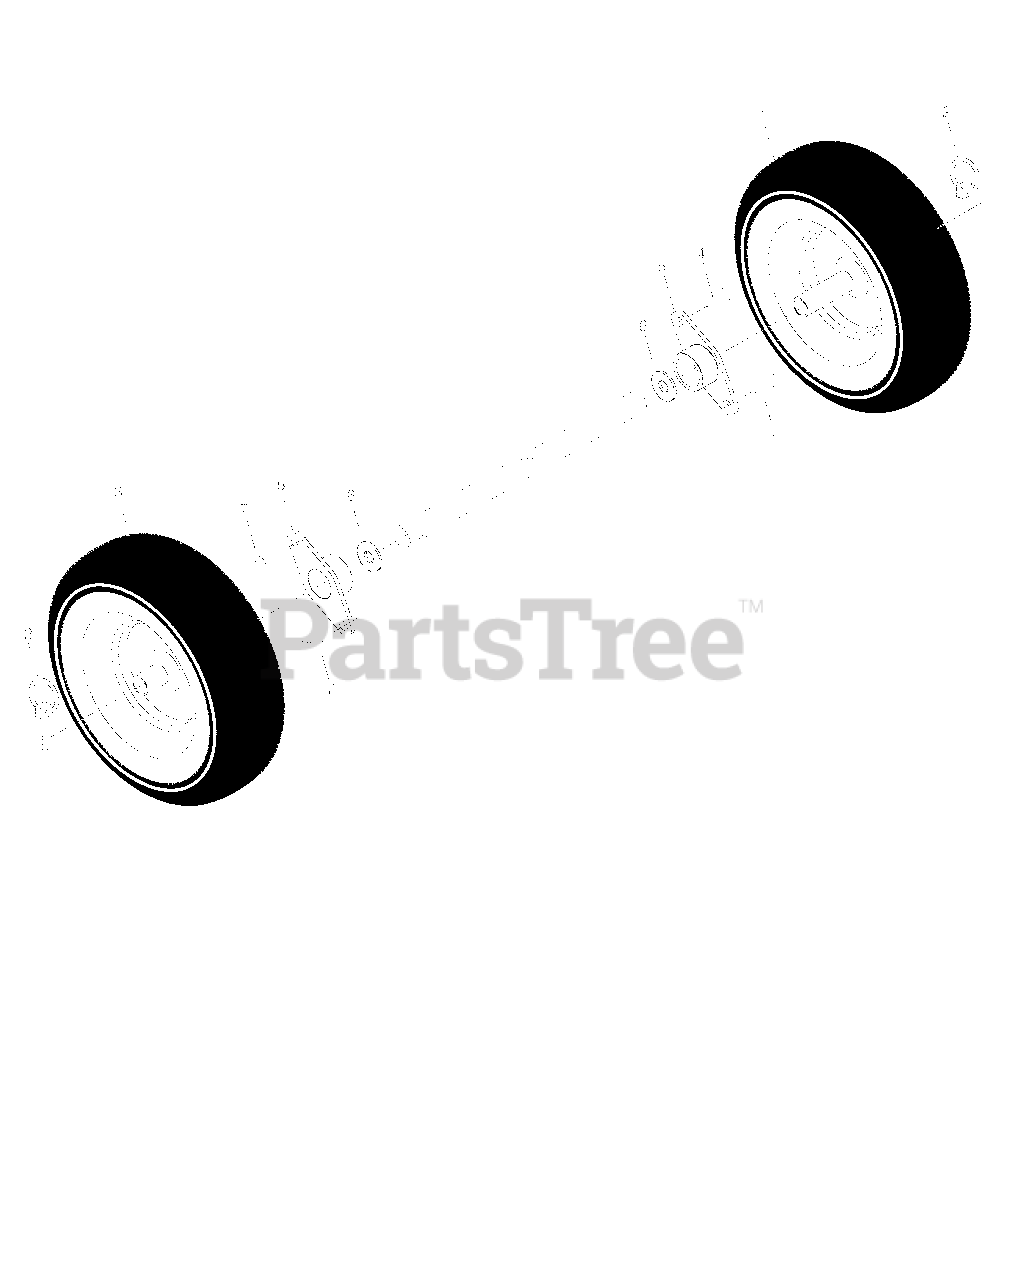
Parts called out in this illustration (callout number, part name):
1	Decal, Danger
2	Decal, Husqvarna
3	Decal, Danger, Deflector
4	Decal, Danger
5	Decal, Husqvarna, 924SBE
6	Decal, Instruction
7	Decal, Traction Lever
8	Decal, Auger Lever
9	Decal, Speed Control
10	Decal, Husqvarna, Crown
